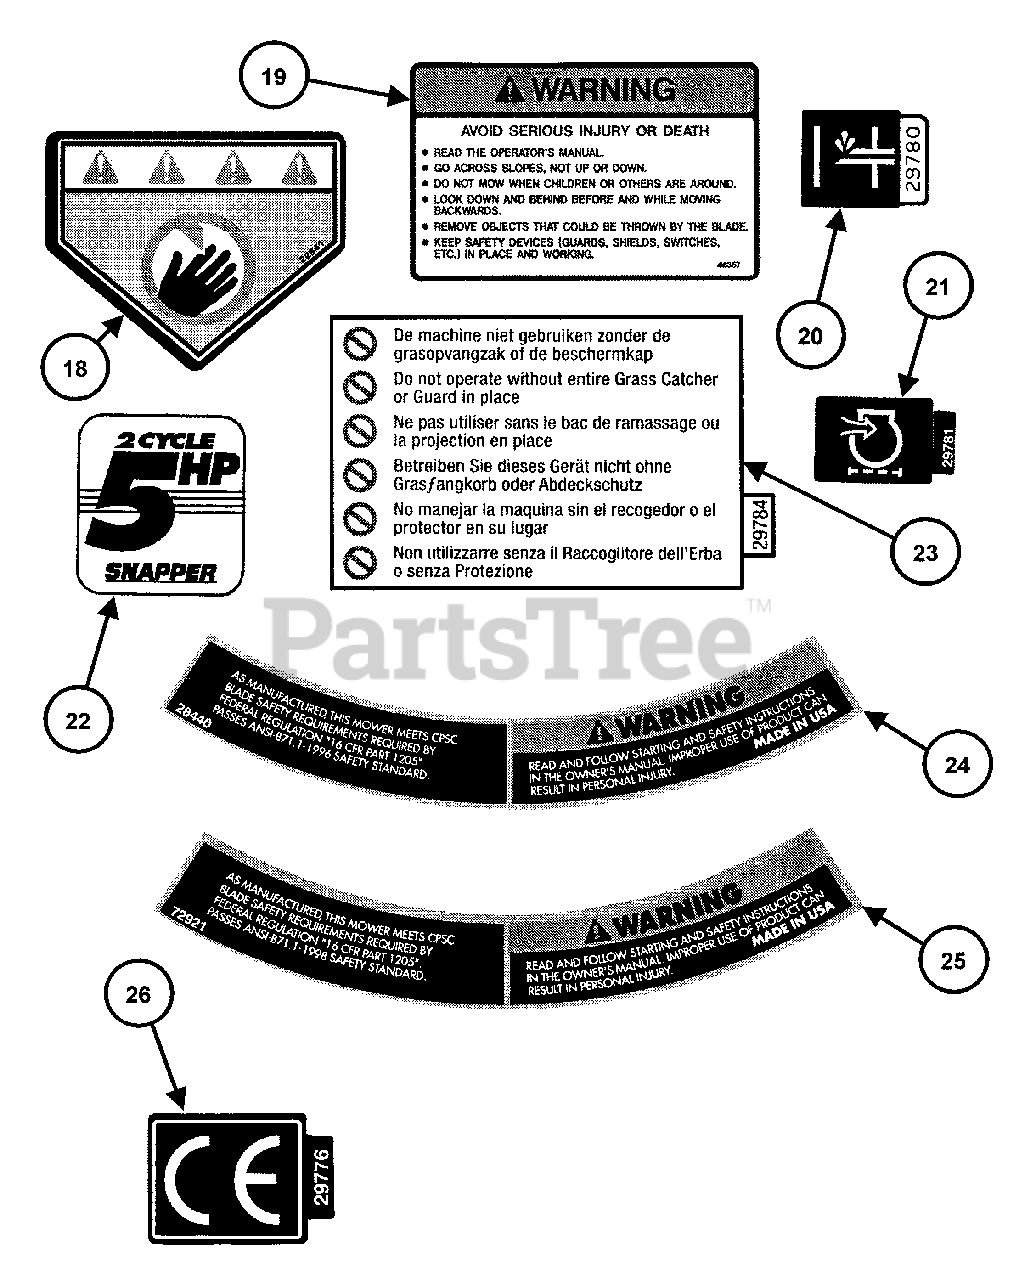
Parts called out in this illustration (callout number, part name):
18	DECAL, Warning
19	DECAL, Warning
20	DECAL, Primer
21	DECAL, Air Filter
22	DECAL, 5 HP 2 Cycle
23	DECAL, Chute
24	DECAL, Warning (Deck)
25	DECAL, Warning (Deck)
26	DECAL, European Community
